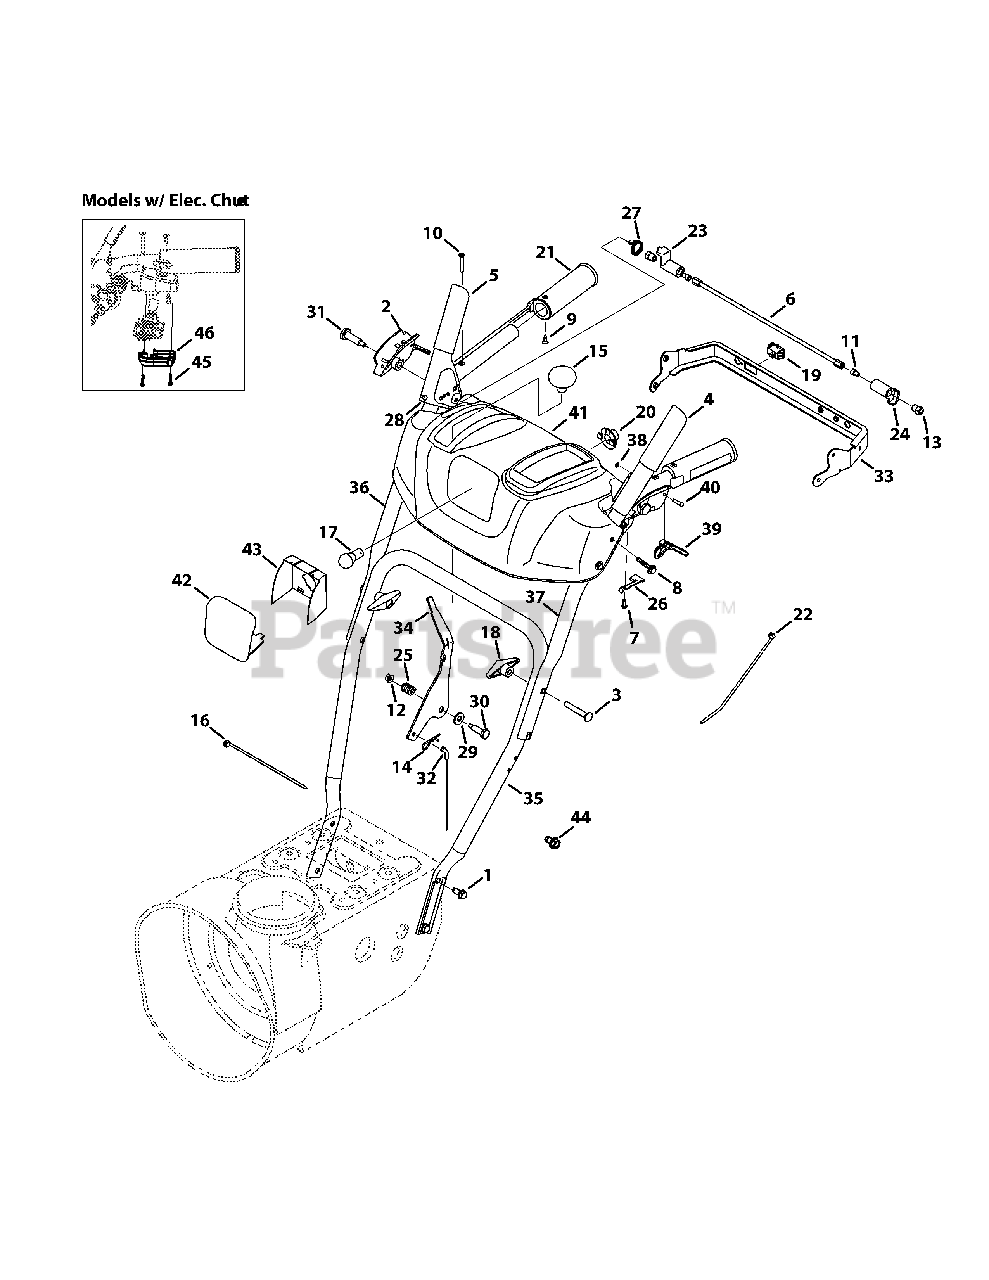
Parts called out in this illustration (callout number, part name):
1	Screw, Taptite, 5/16-18 x .750
2	Clutch Lock, RH
2	Clutch Lock, RH (Elec. Chute)
2	Clutch Lock, LH
3	Screw, Carriage, 5/16-18 x 2.50
4	Auger Engage, Red, LH
5	Drive Engage, Red, RH
7	Screw, Plastite, 8-16 x .50
8	Screw, Taptite, 1/4-20 x 1.625
9	Screw, 10-16 x 0.625
10	Screw, 10-24 x 1.375
11	Screw, 1/4-20 x .50
12	Nut, Flangelock, 1/4-20
13	Nut, Hex, 1/4-20
14	Click Pin, .092 x 1.64
15	Shift Knob
16	Cable Tie, 7"
18	Wing Knob, 5/16-18
19	Heated Grip Switch
20	Lamp Socket
21	Heated Grip
21	Grip, 1.0 ID x 5.0 LG
22	Cable Tie, Push Mount
23	Plate, Lock
24	Cam, Clutch Lock
25	Compression Spring, .39 x .60 x .88
26	Clutch Lock Spring
27	Torsion Spring, 0.8156 x .3038
28	Rubber Bumper
29	Washer, Flat, .385 x .87
30	Screw, Shield, .374 x 1.05
31	Screw, Shoulder, .437 x 1.345 x 1/4-20
32	Speed Selector Cable
36	Upper RH Handle
37	Upper LH Handle
39	Steering Trigger Control, Red
40	Steering Trigger Pin, 3/16
41	Handle Panel, Troy-Bilt
41	Handle Panel, Troy-Bilt Elec. Chute
42	Lens Panel, Troy-Bilt
43	Lens Label, Troy-Bilt
44	Screw, TT, 1/4-20 x .500 (For ground wire)
45	Screw, .159 OD x .610
46	Housing Cover (Elec Chute)
